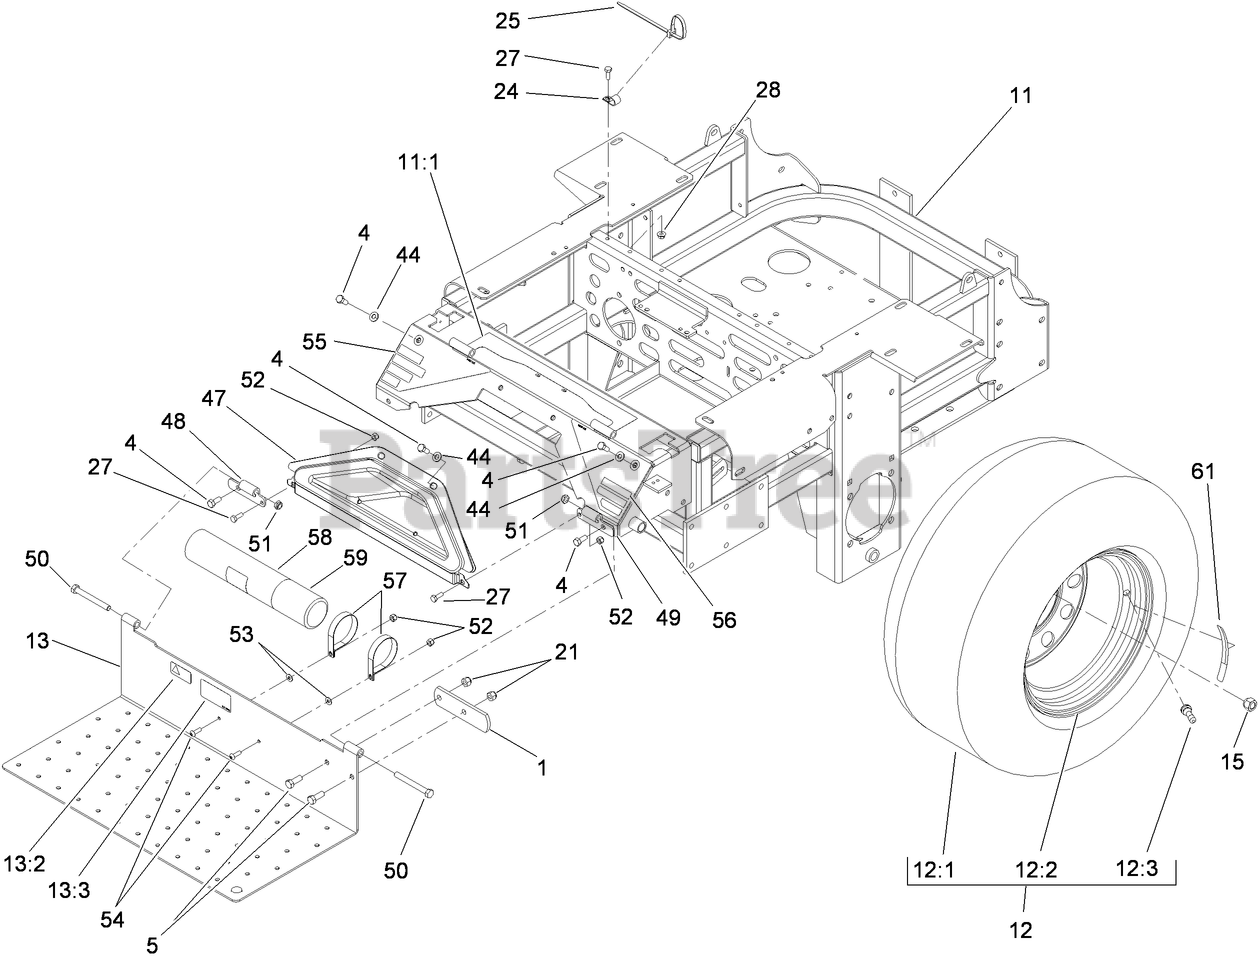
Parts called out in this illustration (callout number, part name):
1	STOP-BRAKE, PARK
4	SCREW-HH
5	SCREW-HH
11	FRAME ASM
11:1	DECAL-CONSOLE, TOP
12	WHEEL AND TIRE ASM
12:3	STEM-VALVE
13	FLOORPAN
13:2	DECAL-PROTECTION, EAR
13:3	Decal-Location, Manual
15	NUT-LUG
21	NUT-LOCK, NI
24	CLIP-LOOM
25	TIE-PLASTIC
27	SCREW-HH
28	NUT-HF
44	WASHER-FLAT
47	Pocket
48	Hinge-Floorpan, LH
49	Hinge-Floorpan, RH
50	SCREW-HH
51	NUT-LOCK, NI
52	NUT-LOCK, NI
53	WASHER-FLAT
54	SCREW-PRH
55	Decal-Warning
56	Decal-Danger
57	R-Clamp
58	TUBE-MANUAL
59	CAP-HOUSING
61	DECAL
